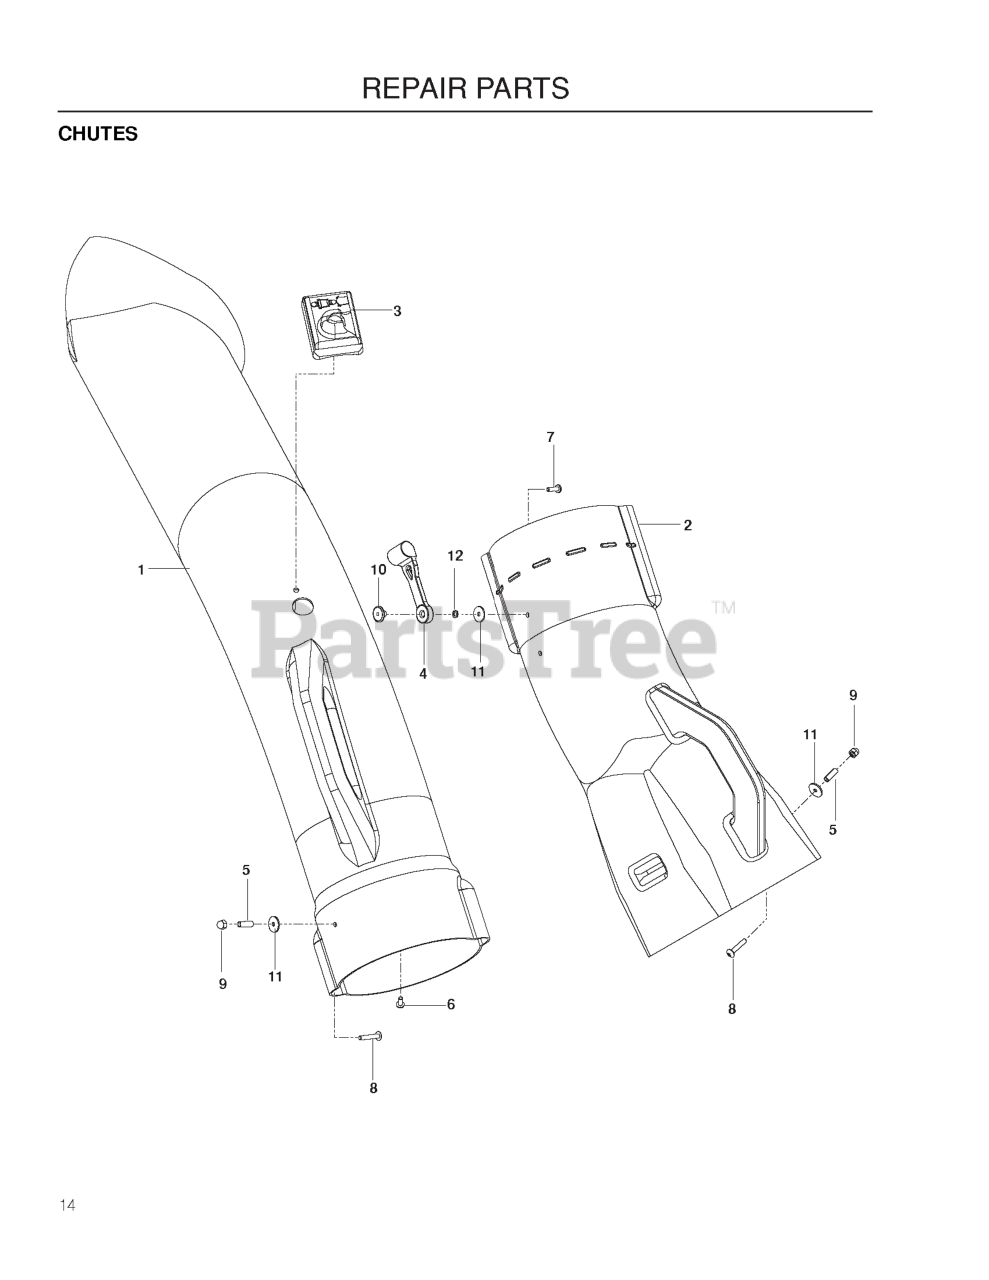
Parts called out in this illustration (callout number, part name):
1	CHUTE.COLLECTION.UPPER
2	CHUTE, MIDDLE
3	INDICATOR ASM BAG
4	HOOD LATCH
5	BSHG .202X.75 LG SPLIT ZD SPEC
6	SCREW
7	SCREW #10-24 X 5/8
8	SCREW #10-24 X 1-1/8 ZD SPEC
9	NUT 10-24 ACORN ZD
10	NUT 10-24 WELD PLATED
12	WASHER - 3/16 LOCK ZD
